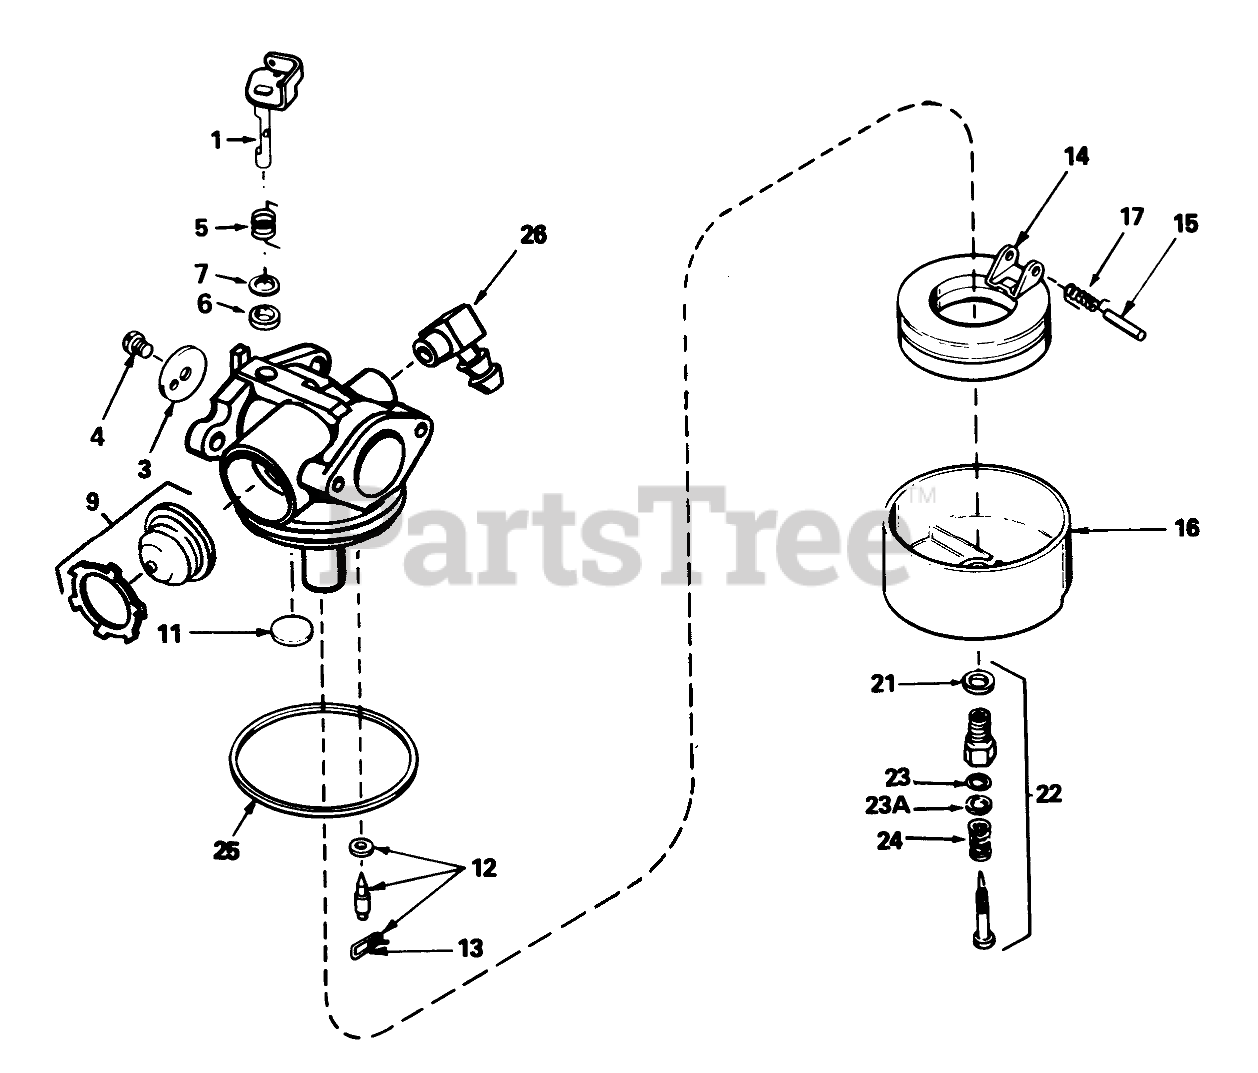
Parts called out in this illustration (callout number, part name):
1	Shaft/Lever-Throttle
3	Shutter-Throttle
4	Screw-Shutter
5	Spring-Trottle, Return
6	Seal-Dust
7	Washer-Seal, Dust
9	Bulb-Primer
11	Plug-Welch, Atmospheric Vent
12	Inlet Needle Assembly (Incl. Ref. #13)
13	Clip-Spring
14	Float
15	Shaft-Float
16	Bowl-Float (no drain)
17	Spring-Float, Dampening
21	Washer-Bowl Nut
22	Main Adjust Screw Assy. (Incl. Ref. #21, 23, 23A & 24)
23	"O"Ring
25	O Ring-Bowl, Float
26	Fitting-Fuel
